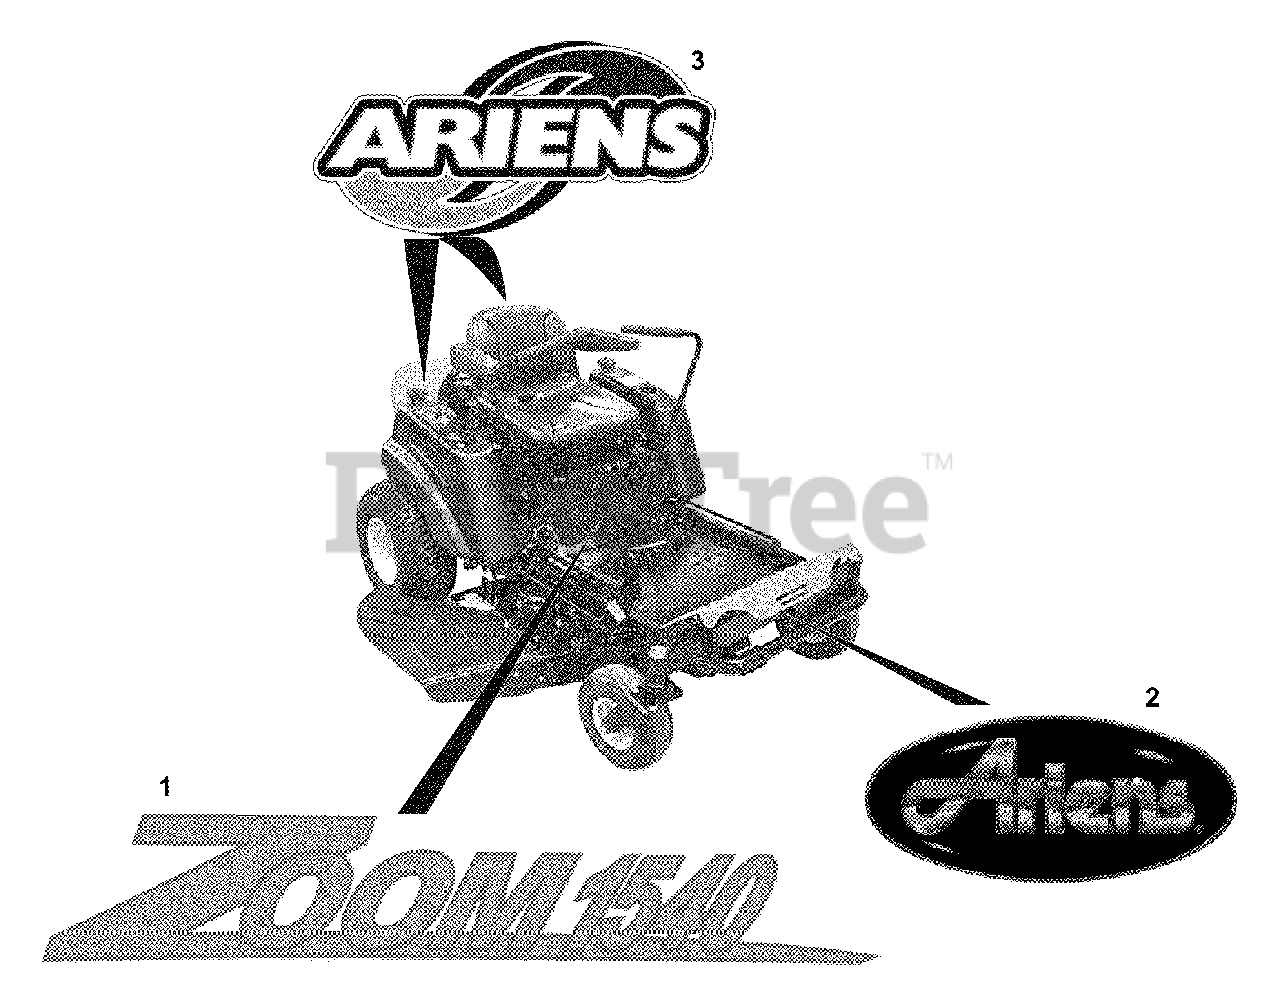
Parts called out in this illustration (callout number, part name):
1	DECAL, ZOOM 1540
2	DECAL-ARIENS JEWEL
3	DECAL ZOOM HOOD
